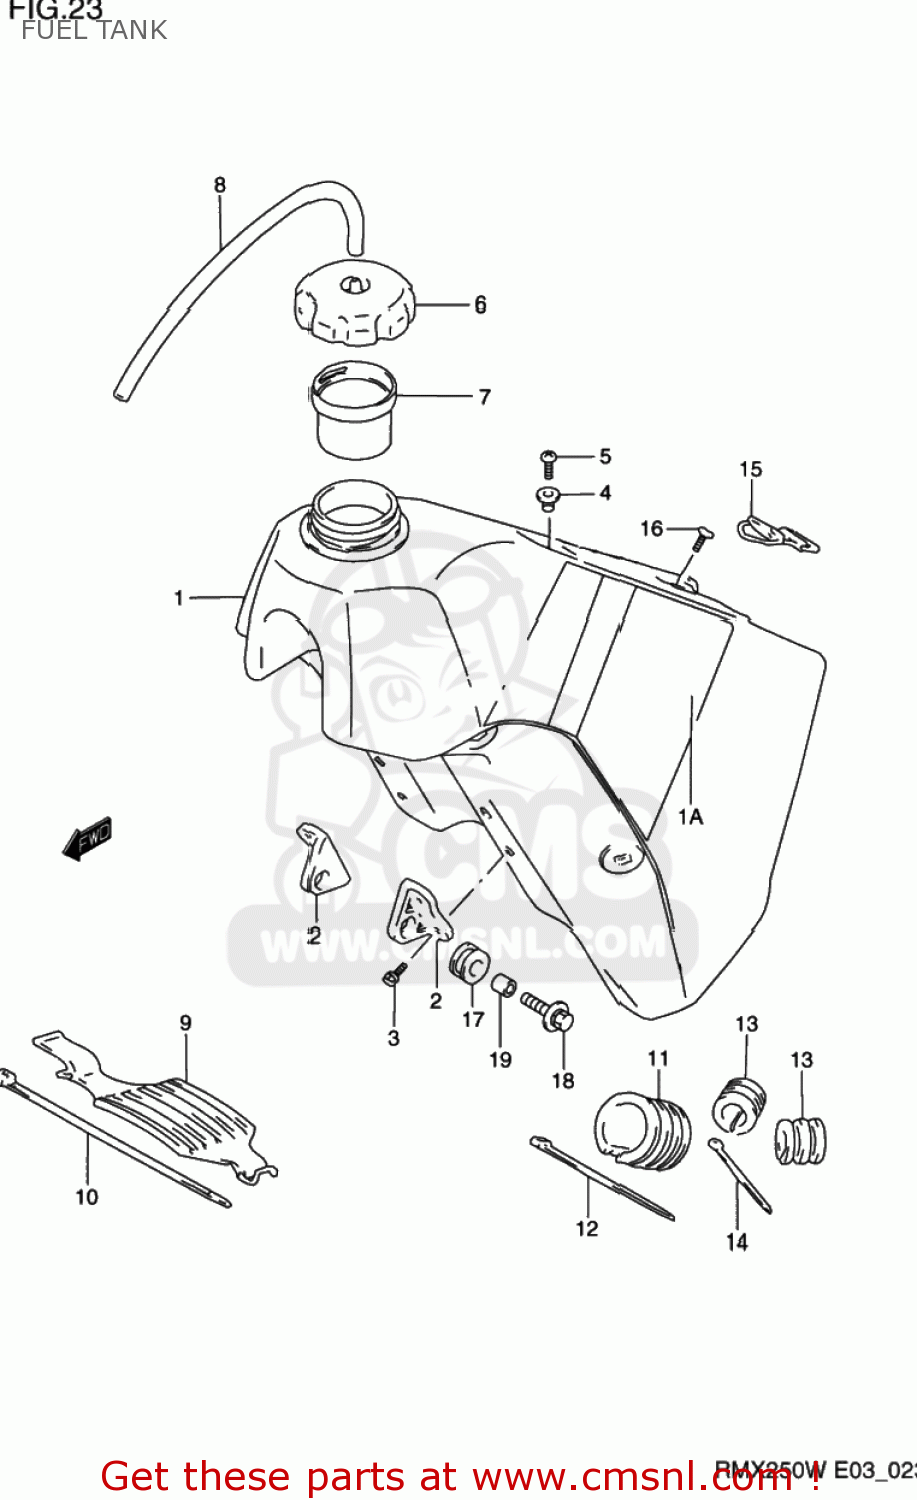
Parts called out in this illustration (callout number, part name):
1	TANK COMP,FUEL
1A	TAPE SET,FUEL TANK
2	BRACKET,FUEL TANK FR
3	BOLT
4	HOOK,SEAT FR
5	SCREW
6	CAP ASSY,FUEL TANK
7	TUBE,FILLER INLET
8	HOSE(5X8.2X600)
9	CUSHION,FUEL TANK NO.1
10	CLAMP(L:250)
11	CUSHION,FUEL TANK NO.2
12	CLAMP(L:300)
13	CUSHION,FUEL TANK NO.1
14	CLAMP(L:145)
15	BAND,FUEL TANK RR
16	SCREW
17	CUSHION
18	BOLT(8X30)
19	SPACER(8.5X12X13.5)
